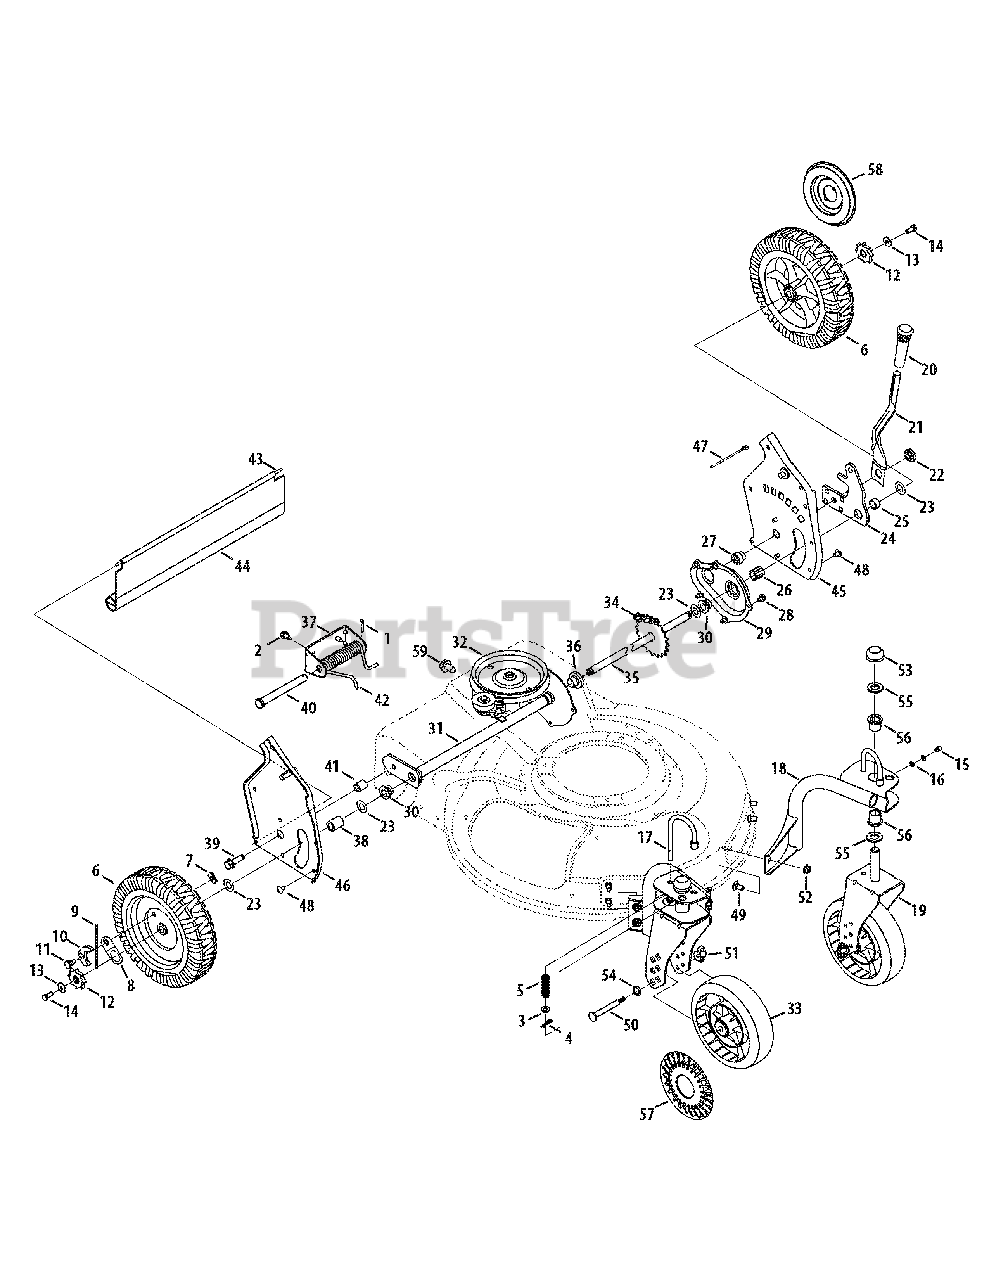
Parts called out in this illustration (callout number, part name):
1	Cotter Pin
2	Screw 1/4-14 x .825
3	Flat Washer.330 ID x.630 OD
4	Cotter Pin
5	Compression Spring
6	Wheel, 9 x 2.125
7	Top Lock Tab Weld Nut 1/4-20
8	Ratchet Pawl Plate
9	Plastic Spring Ratchet
10	Pawl LH
11	Shlder Screw.340 ID x.285 OD
12	Wheel Ratchet
13	Bell Washer.265 ID x.75 OD
14	Hex Cap Screw 1/4-20 x.620
15	Grease Fitting
16	Flat Washer.203 ID x.403 OD
17	Wheel Pin Lock
21	Spring Lever
22	Shoulder Nut.825 x .165 Lg.
23	Flat Washer .508 ID x 1.0 OD
25	Spacer .510 ID x .70 OD
26	Slv Bearing .504 ID x .830 OD
27	Shlder Spacer, .385ID x .715Lg
28	Tap Screw 1/4-20 x .375
32	Transmission Ass’y Complete
33	Wheel 7 x 2
34	Chain
35	Rear Axle Assembly
36	Flge Bearing .506 ID x .715 Lg
39	Screw 3/8-16 x .25
40	Clevis Pin .50 Dia x 4.82 Lg.
41	Spacer .385 ID x .624 OD
42	Torsion Spring
43	Trail Shield Wire
44	Trail Shield
48	Screw 1/4-14 x.500
49	Carriage Bolt 5/16-18 x.62
50	Caster Axle
51	Wing Nut
52	Flange Lock Nut 5/16-18
54	Wave Washer.531 ID x.781 OD
55	Flat Washer.640 ID x 1.12 OD
56	Flange Bearing
57	Hubcap - Spoke w/ Hole
58	Hubcap - Radial Spoke
59	Screw, 5/16-18 x .625
